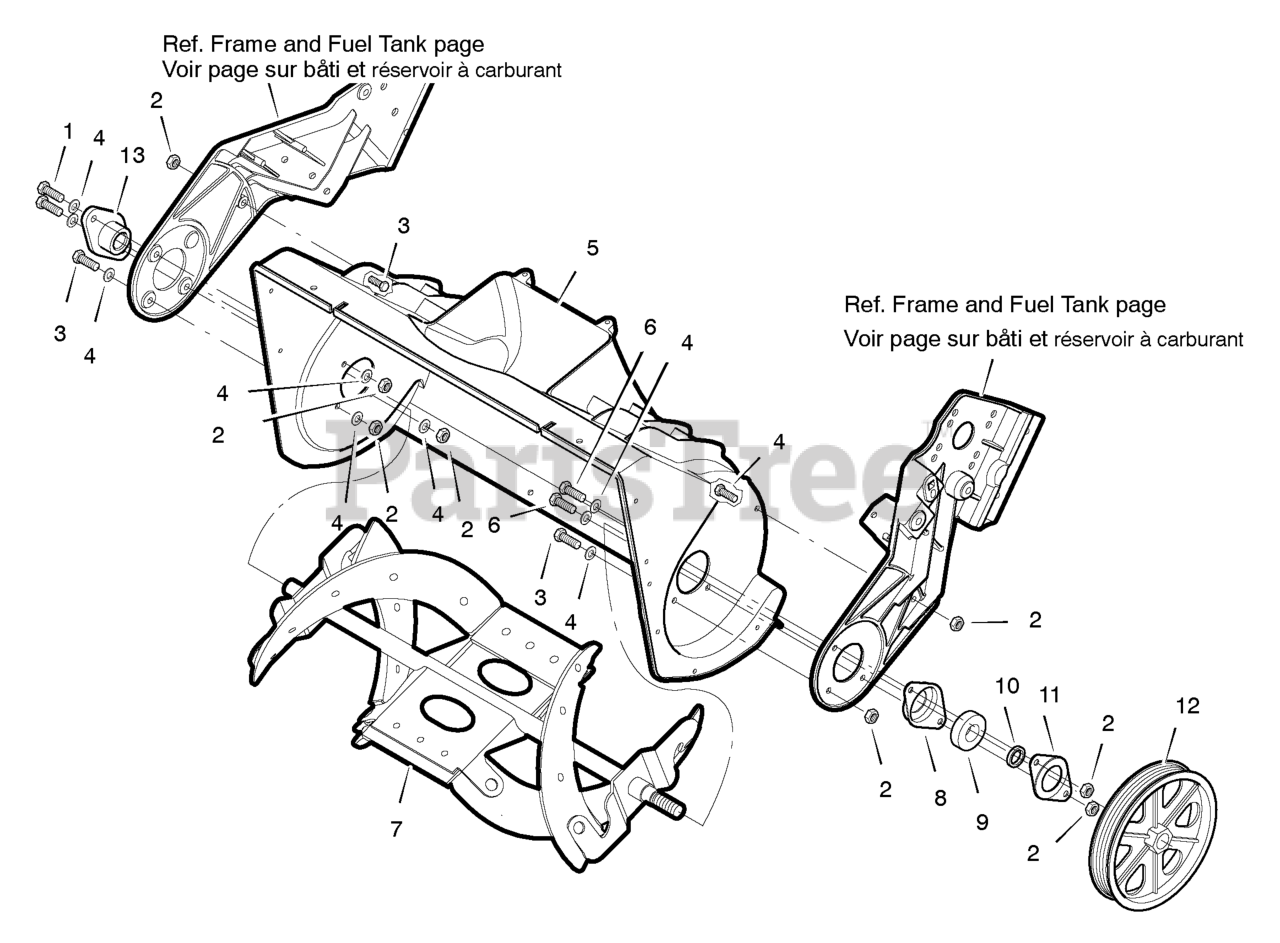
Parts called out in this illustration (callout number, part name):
1	Screw, 1/4-20 x 1.00
2	Nut, Hex 1/4-20
3	Screw, 1/4-20 x .75
4	Washer, Flat
5	Housing Assembly, Auger
6	Screw, 1/4-20 x .63
7	Auger Assembly, 22"
8	Retainer, Bearing
9	Bearing
10	Sleeve, Spacer
11	Plate, Bearing Retainer
12	Pulley, Auger Drive V6
13	Bearing, Flange
